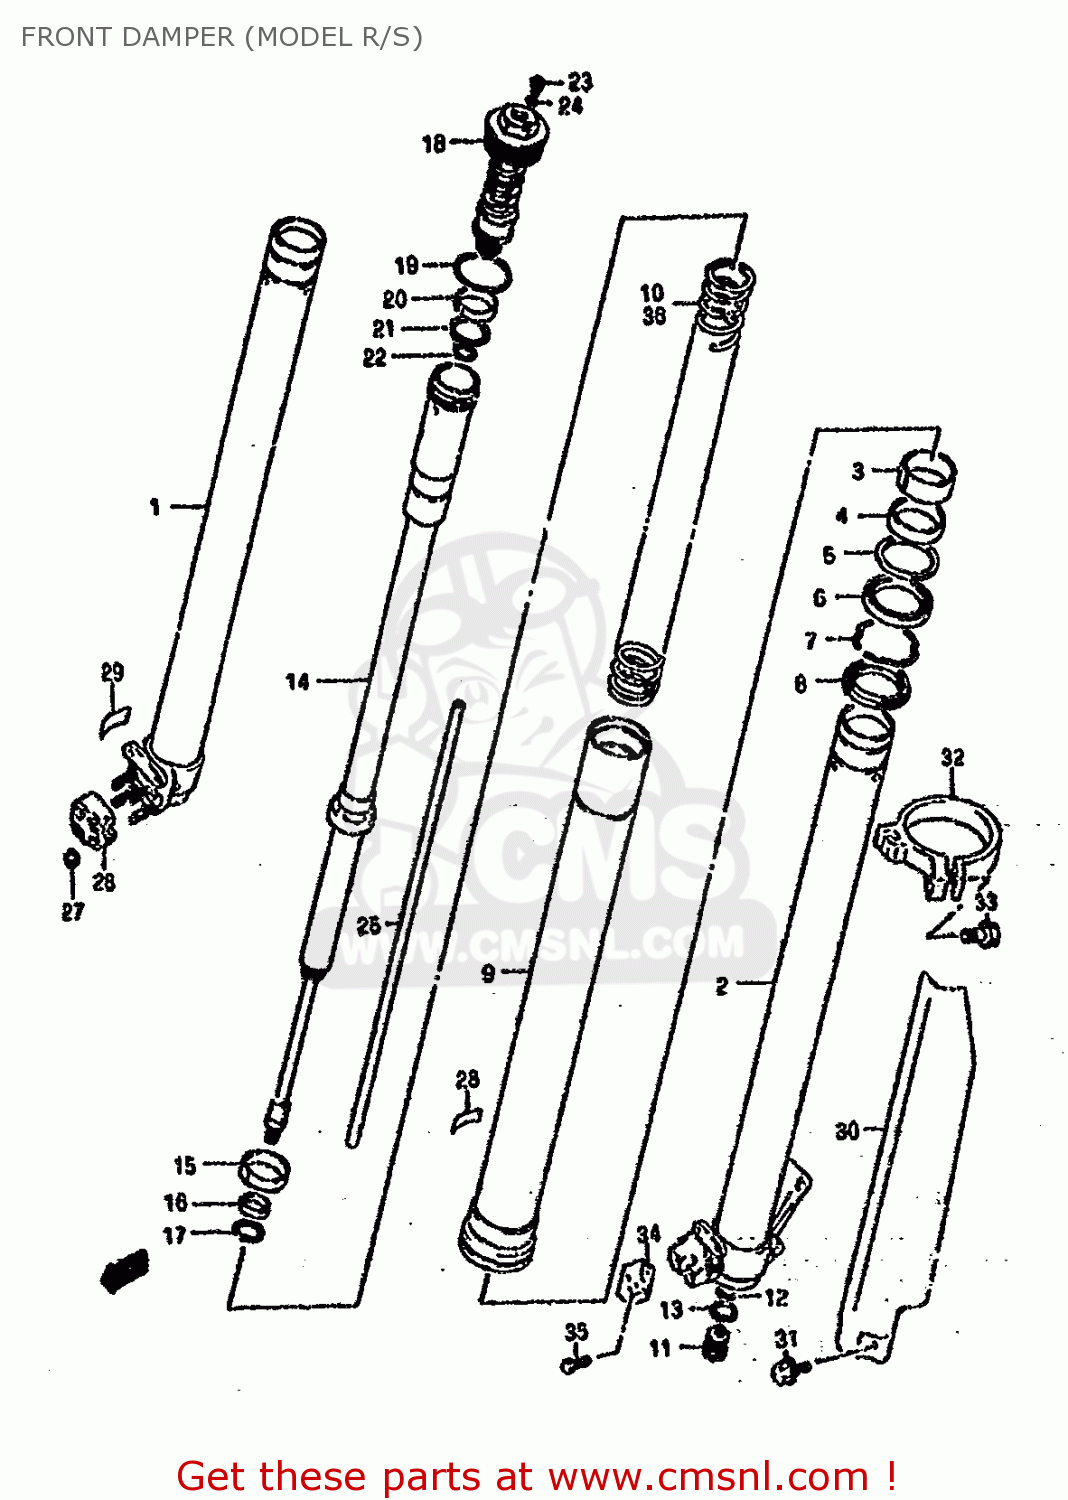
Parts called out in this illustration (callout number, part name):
1	TUBE,INNER,RIGHT
2	TUBE,INNER,LEFT
3	BUSH,SLIDE
4	BUSH,GUIDE
5	SPACER,SEAL
6	SEAL,OIL
7	RING,OIL SEAL STOPPER
8	SEAL,DUST
9	TUBE,OUTER
10	SPRING,MAIN
11	BOLT,CTR
12	GASKET (NAS)
13	O RING,CTR BOLT
14	DAMPER,CARTRIDGE
15	BUSH,DAMPER SLIDE
16	VALVE,OIL LOCK
17	RING,VALVE STOPPER
18	BOLT,FORK
19	O RING
20	BUSH,FORK BOLT SLIDE
21	O-RING,FORK BOLT,CENTER
22	O-RING,FORK BOLT,LOWER
23	BOLT,PLUG
24	O RING,PLUG
25	ROD,PUSH
26	HOLDER,AXLE,R
27	NUT
28	LABEL
29	LABEL
30	PROTECTOR ,RH.
31	BOLT
32	GUIDE,FORK PROTECTOR
33	BOLT
34	GUIDE,HOSE,L
35	BOLT
36	SPRING,MAIN
